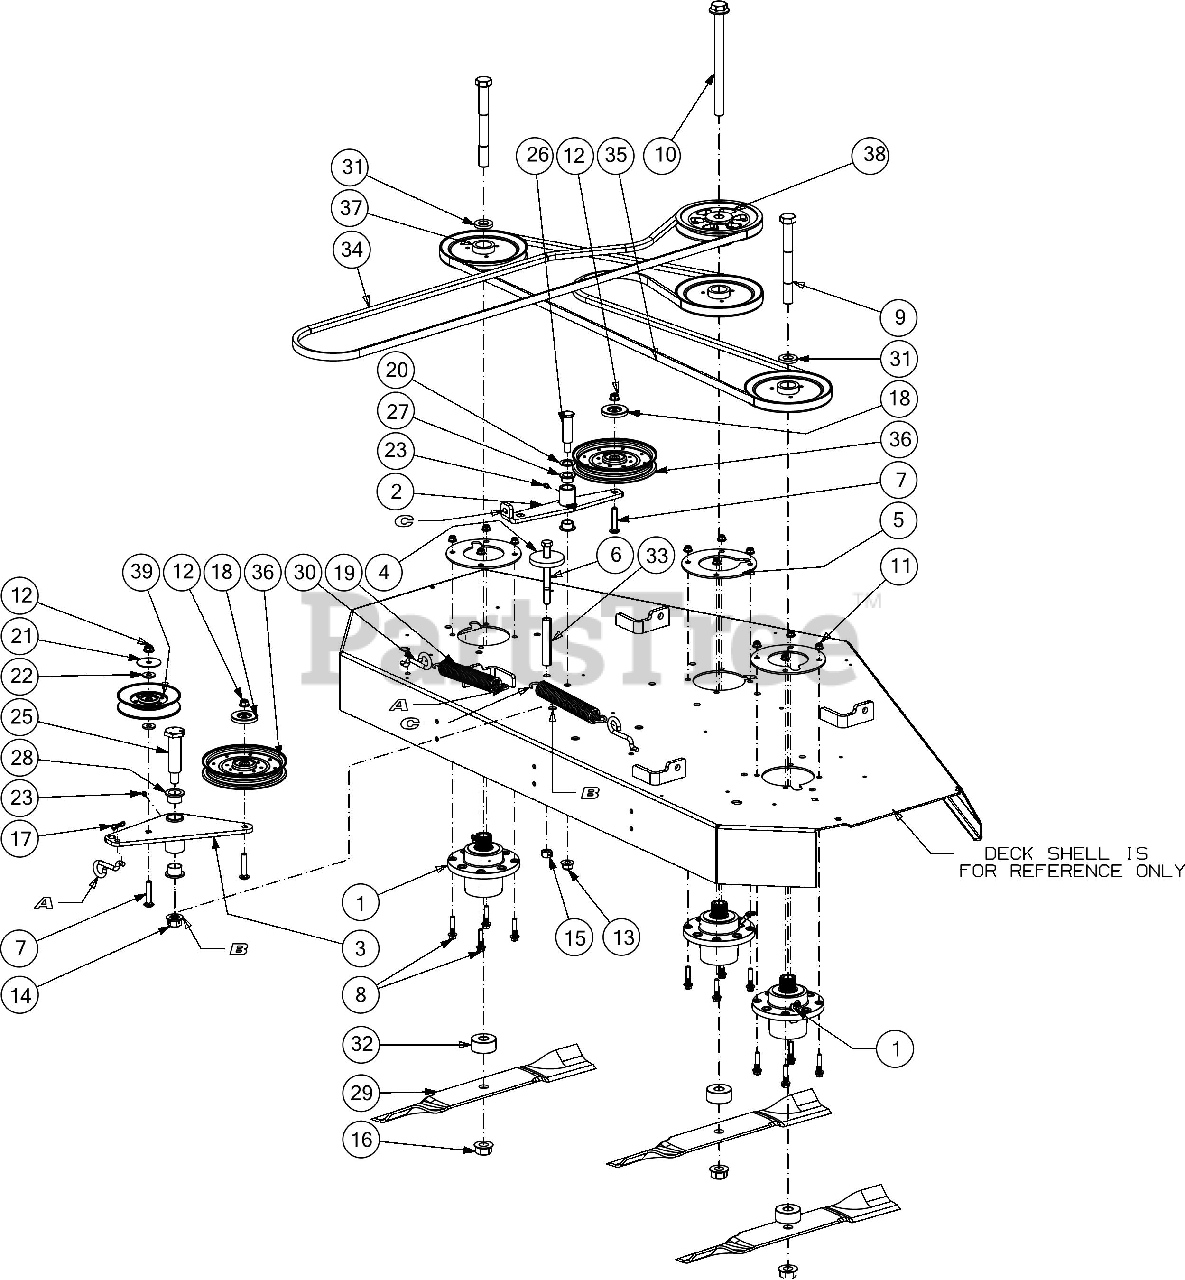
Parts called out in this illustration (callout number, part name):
1	SPINDLE ASSEMBLY
2	IDLER BRACKET
3	PTO IDLER ASSEMBLY
4	SPACER PLATE
5	SPINDLE TOP SUPPORT PLATE
6	BOLT-HEX 1/2-13X5.0 GR5
7	CARRIAGE BOLT 3/8-16 X 2
8	BOLT 5/16-18 X 1.50 GR5
9	SCREW 3/4-16 X 7.00 GR5
10	SCREW 3/4-16 X 9.00 GR5
11	FLANGE LOCK NUT 5/16-18
15	HEX NUT CTR LK 1/2-13
16	HEX FLANGE NUT 3/4
17	BOW TIE COTTER PIN 1/4-5/16
18	PULLEY CAP
19	EXTENSION SPRING
20	FLAT WASHER .793ID X 1.24OD X .060
21	HUB CAP WASHER .406 X 1.92 X .060
22	FLAT WASHER .406ID X1.0 OD
23	GREASE FITTING
25	SHOULDER SCREW 1.0 X 3.15
26	SHOULDER SCREW
27	FLANGE BEARING
29	21" BLADE (HI LIFT)
31	SPACER .812 ID X .218 LG
36	IDLER PULLEY
37	SPINDLE PULLEY 7"
38	PULLEY-7.01 OD X .75 ID
39	IDLER PULLEY 5.06 OD
